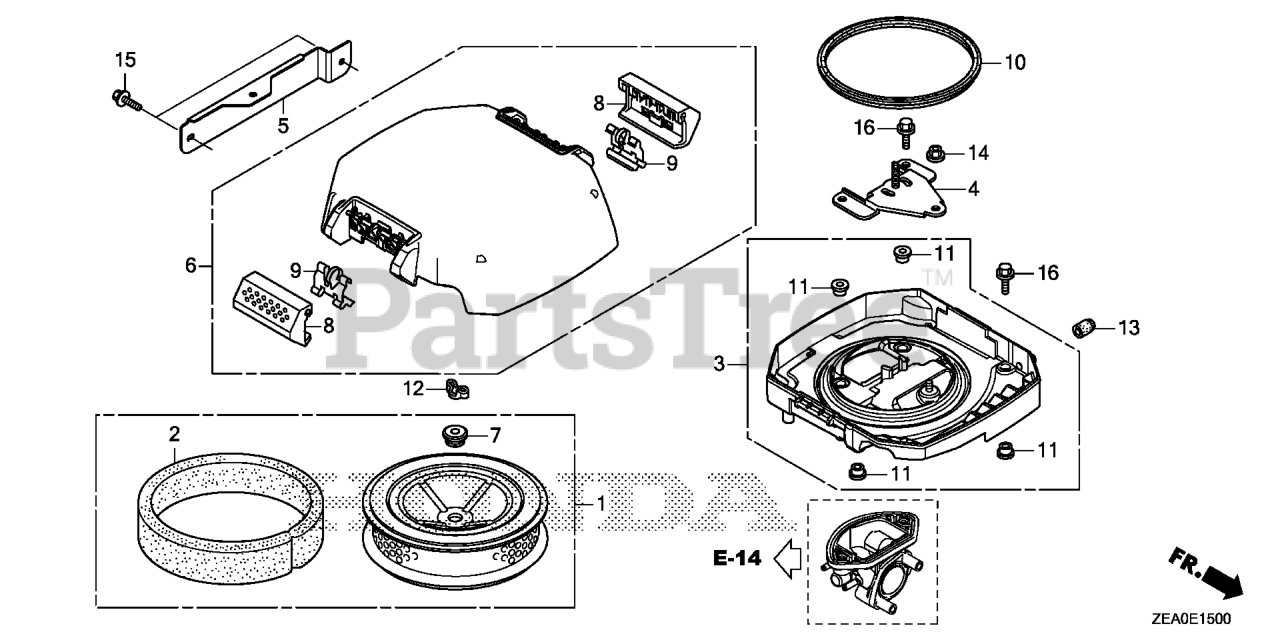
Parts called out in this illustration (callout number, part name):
1	ELEMENT, AIR CLEANER
2	FILTER (OUTER)
3	HOUSING, AIR CLEANER
4	STAY, AIR CLEANER ELEMENT
5	STAY B, AIR CLEANER
6	COVER, AIR CLEANER
7	GROMMET, AIR CLEANER
8	KNOB, AIR CLEANER COVER
9	SPRING, AIR CLEANER HOUSING COVER
10	GASKET, AIR CLEANER HOUSING
11	COLLAR, FAN COVER
12	WINGNUT, TOOL BOX SETTING
13	CAP, SEALING
14	NUT, FLANGE (6MM)
15	BOLT, FLANGE (6X16) Use from Engine SN 2056820.
16	BOLT, FLANGE (6X18)
